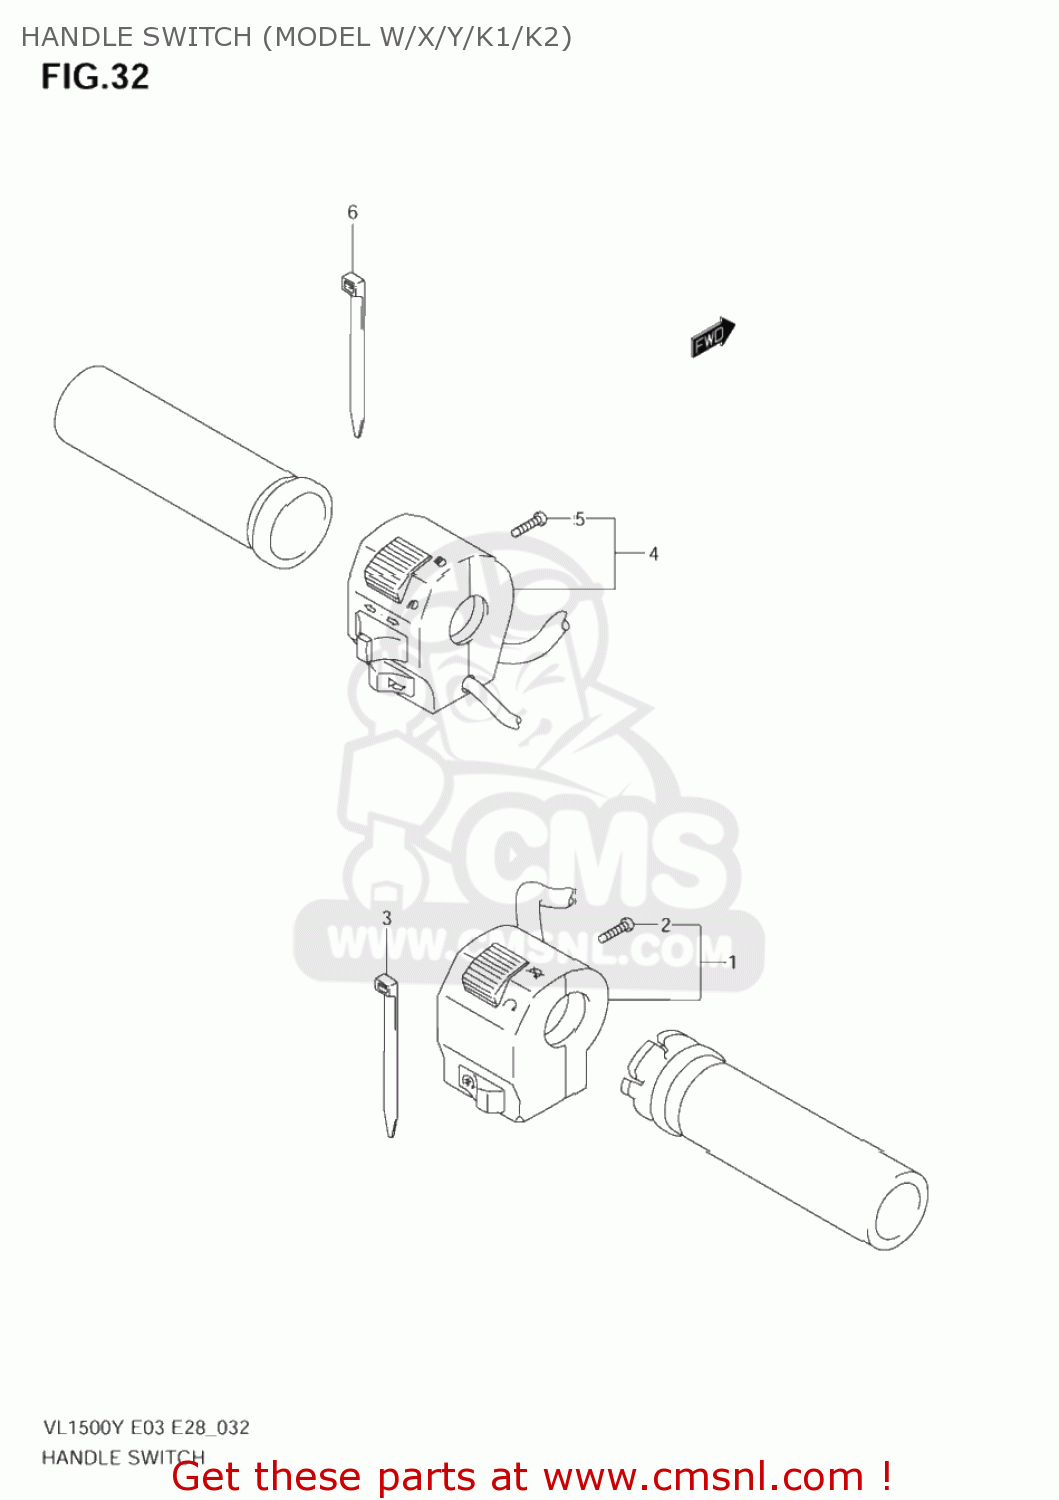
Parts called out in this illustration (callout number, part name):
1	SWITCH ASSY,HANDLE,R
2	SCREW
3	CLAMP(L:145)
4	SWITCH ASSY,HANDLE,L
5	SCREW
6	CLAMP(L:145)
